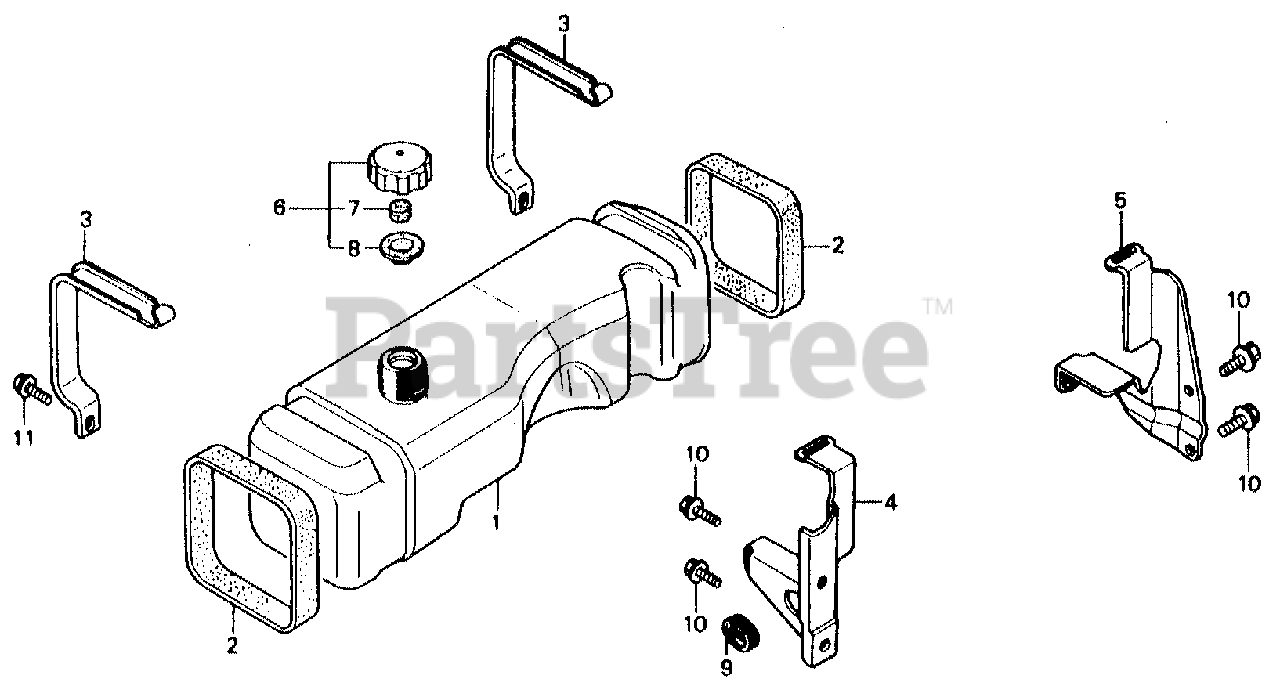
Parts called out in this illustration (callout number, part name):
1	TANK, FUEL (NOT AVAILABLE)
2	RUBBER, FUEL TANK MOUNTING
3	BAND, TANK MOUNTING
4	STAY A, TANK
5	STAY B, TANK
6	CAP, FUEL TANK
7	SPONGE, FUEL CAP BREATHER
8	GASKET, FUEL CAP
9	GROMMET, WIRE
10	BOLT, FLANGE (6X16)
11	BOLT, FLANGE (6X16)
